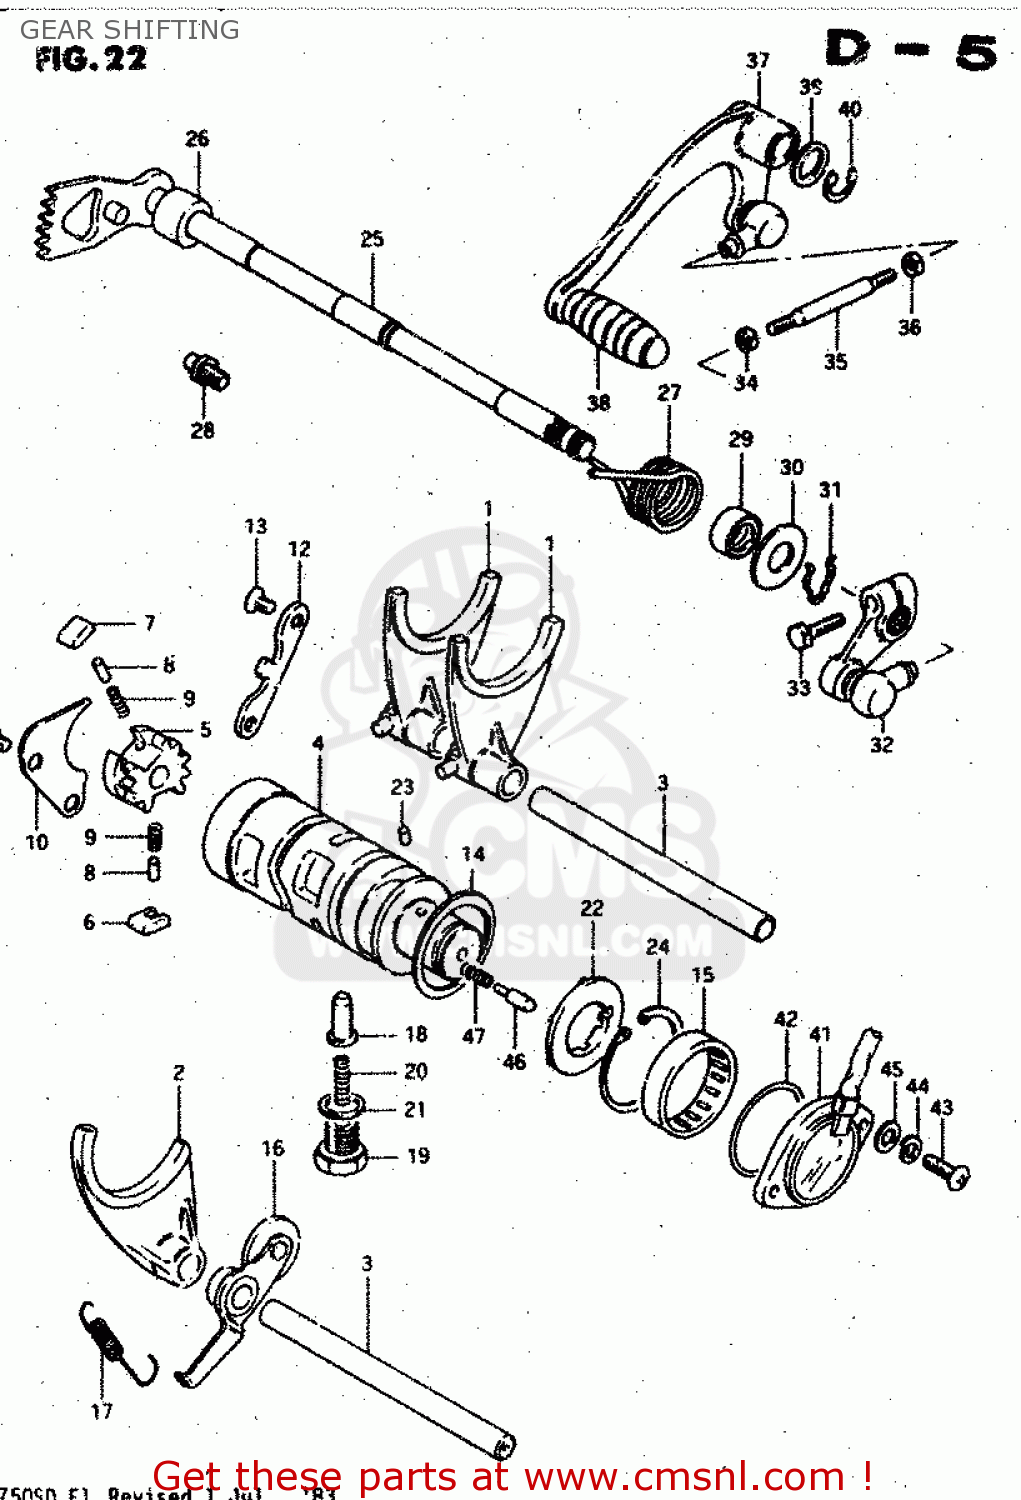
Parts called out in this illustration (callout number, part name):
1	FORK,GEAR SHIFT NO.1
2	FORK,GEAR SHIFT NO.3
3	SHAFT,GEAR SHIFT FORK
4	CAM,GEAR SHIFT
5	SHIFTER,GEAR SHIFT CAM
6	PAWL,GEAR SHIFT NO.1
7	PAWL,GEAR SHIFT NO.2
8	PIN(5X8)
9	SPRING
10	LIFTER,GEAR SHIFT PAWL
11	SCREW
12	GUIDE,GEAR SHIFT CAM
13	SCREW
14	WASHER(40X45X1)
15	BEARING(25X32X12)
16	STOPPER,GEAR SHIFTING
17	SPRING
18	STOPPER,GEAR SHIFT CAM NO.2
19	HOLDER,GEAR SHIFT CAM STOP SPR
20	SPRING
21	GASKET(14X19.2X2) (NAS)
22	PLATE,GEAR SHIFT CAM STOPPER
23	PIN 4X6
24	CIRCLIP,25MM
25	SHAFT,GEAR SHIFT
26	SPACER(12X20X15.3)
27	SPRING
28	STOPPER,GEAR SHIFT CAM
29	OIL SEAL
30	WASHER (12.5X27X1.6)
31	SPRING,RETAINER
32	ARM,GEAR SHIFT
33	BOLT
34	NUT
35	ROD,GEAR SHIFT LINK
36	NUT
37	LEVER ASSY,GEA
38	RUBBER,PEDAL
39	WASHER
40	CIRCLIP
41	TERMINAL BASE,NEUTRAL SWITCH
42	O-RING (D:2.4 ID:26.2)
43	SCREW 5X20
44	LOCK WASHER
45	WASHER
46	PIN(5X15.5)
47	SPRING
